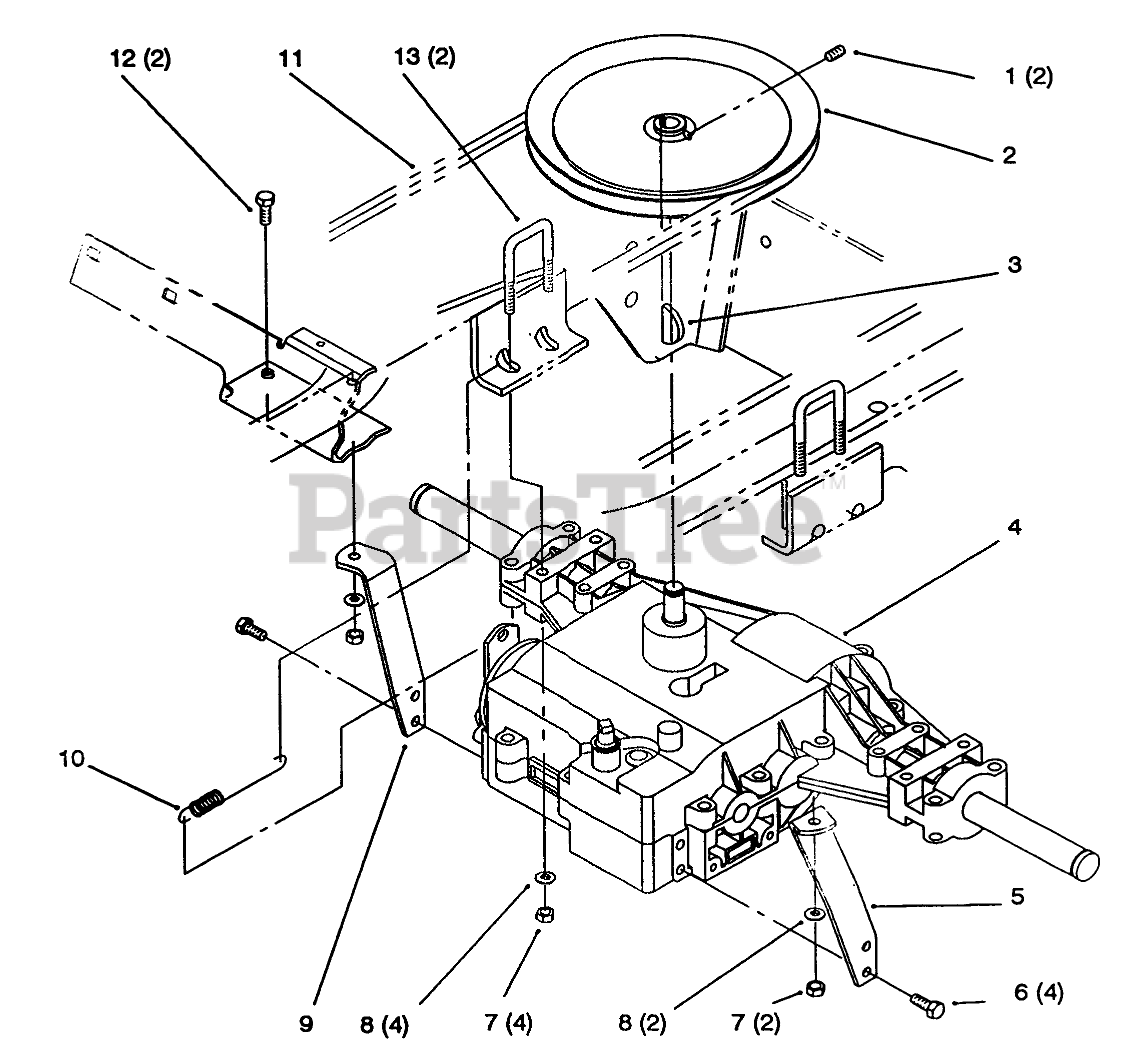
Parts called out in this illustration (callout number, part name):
1	Screw-Set (Only On: 72042, 72062)
2	Pulley (Only On: 72042, 72062)
3	Key (Only On: 72042, 72062)
4	Transaxle-Peerless 820 (Only On: 72042, 72062)
5	Strap-Torque LH (Only On: 72042, 72062)
6	Screw-TAP (Only On: 72042, 72062)
7	Nut-Hex Lock (Only On: 72042, 72062)
8	Washer-Flat (Only On: 72042, 72062)
9	Strap-Torque RH (Only On: 72042, 72062)
10	Spring-Extension (Only On: 72042, 72062)
11	Belt-Gear (Only On: 72042, 72062)
12	Screw-HH (Only On: 72042, 72062)
13	U-Bolt (Only On: 72042, 72062)
